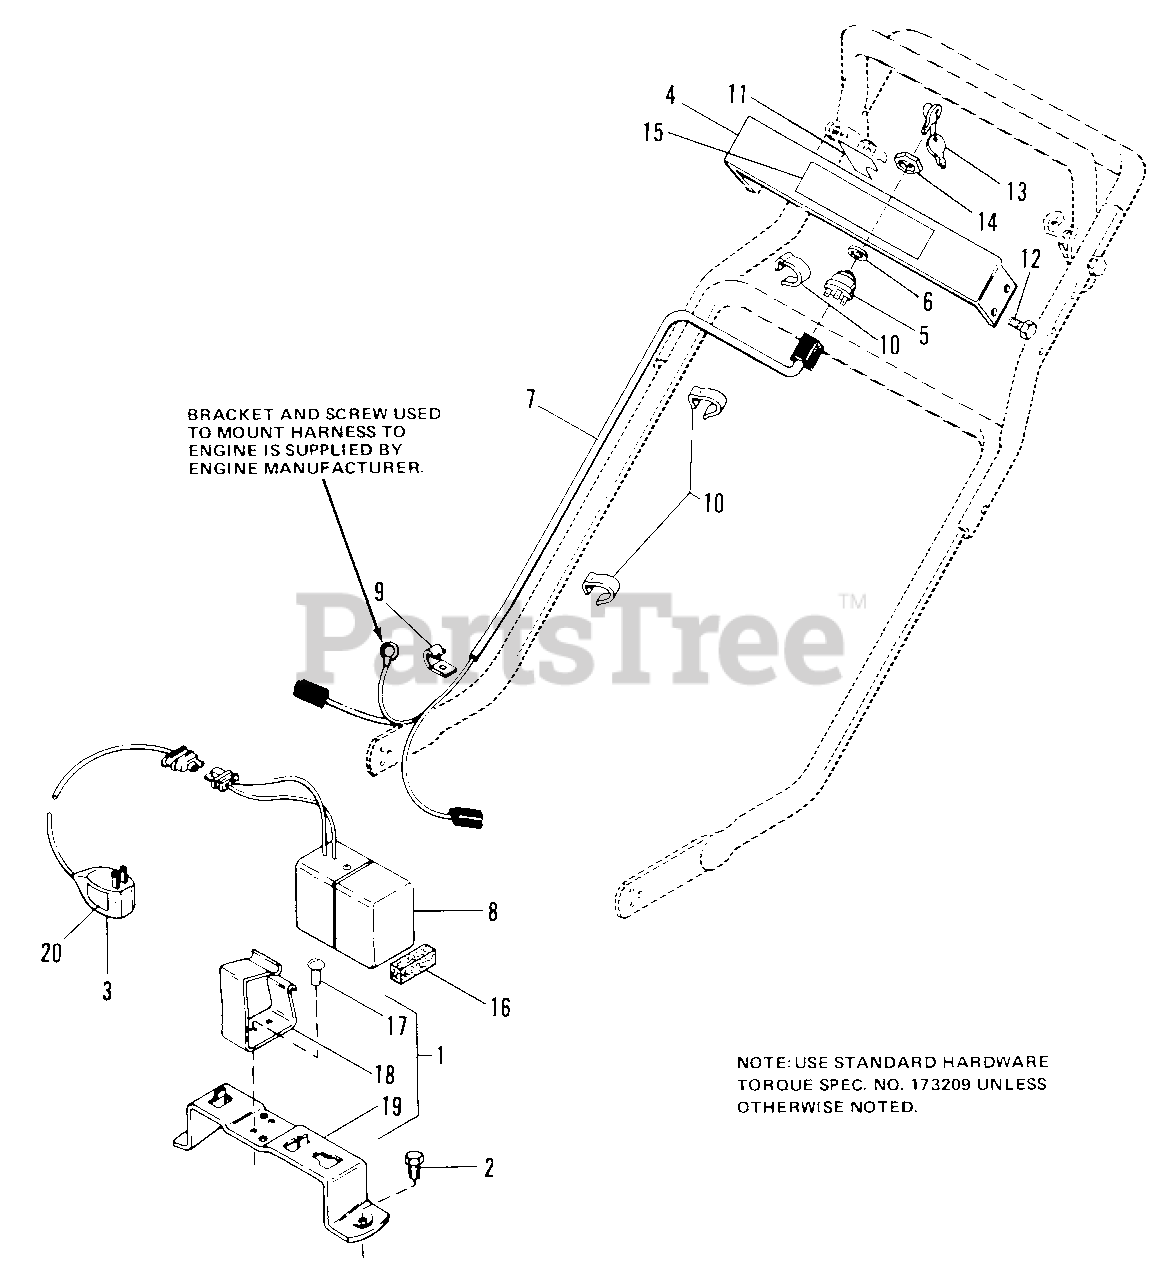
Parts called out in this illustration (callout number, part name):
1	SUPPORT ASSY, Battery
2	SCREW, Taptite, 1/4-20 x 3/8
3	CHARGER, Battery
4	SWITCH, Mfg. Panel
5	KEY, Switch
6	LOCKWASHER, Internal
7	HARNESS ASSY
9	CLAMP, Cable
10	CLIP, Harness
11	DECAL, Ignition
12	SCREW, Taptite, 1/4-20 x 3/8
13	KEY & RING ASSY (Set of Two)
14	NUT, Hex, Special
15	DECAL, Simplicity Electric Start
17	RIVET, Pop
18	CLIP, Spring, Battery
19	SUPPORT, Battery
20	DECAL, Caution
